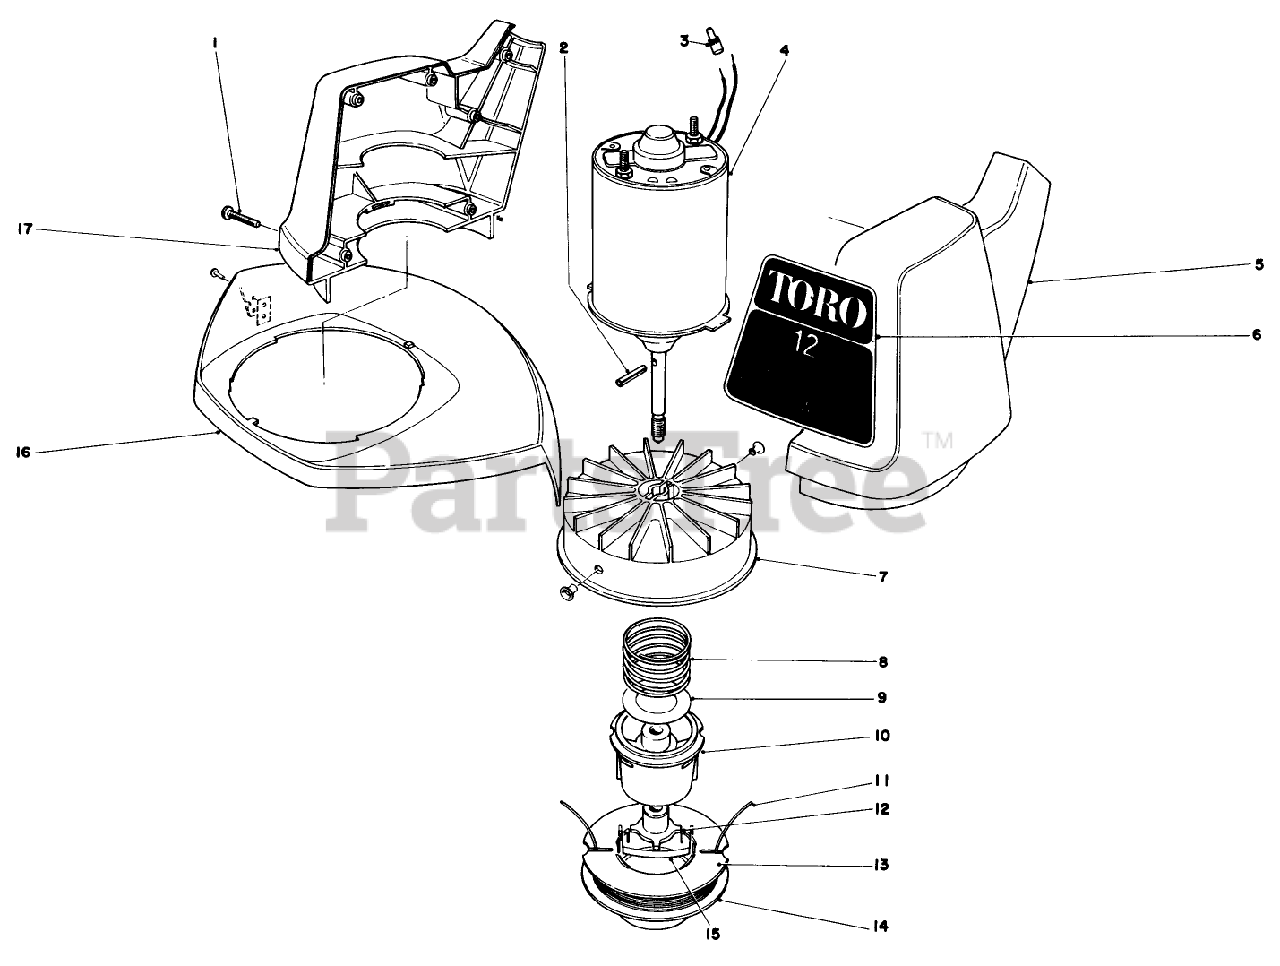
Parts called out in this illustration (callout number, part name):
1	SCREW-PPH
2	COIL PIN
3	Connector
4	Motor D.C.
5	Housing-L.H.
6	Decal-Commercial Duty
7	Drum W/Eyelets
8	SPRING COMPRESSION
9	WASHER-FLAT
10	SPOOL CORE
11	50-Coil.065" Cutting Line
12	Driver
13	Empty SPooI
14	50-,.065" Dia. Line Prewound On Spool
15	SADDLE-SPOOL CAP
16	Shield with Cut Off Blade
17	Housing-R.H.
